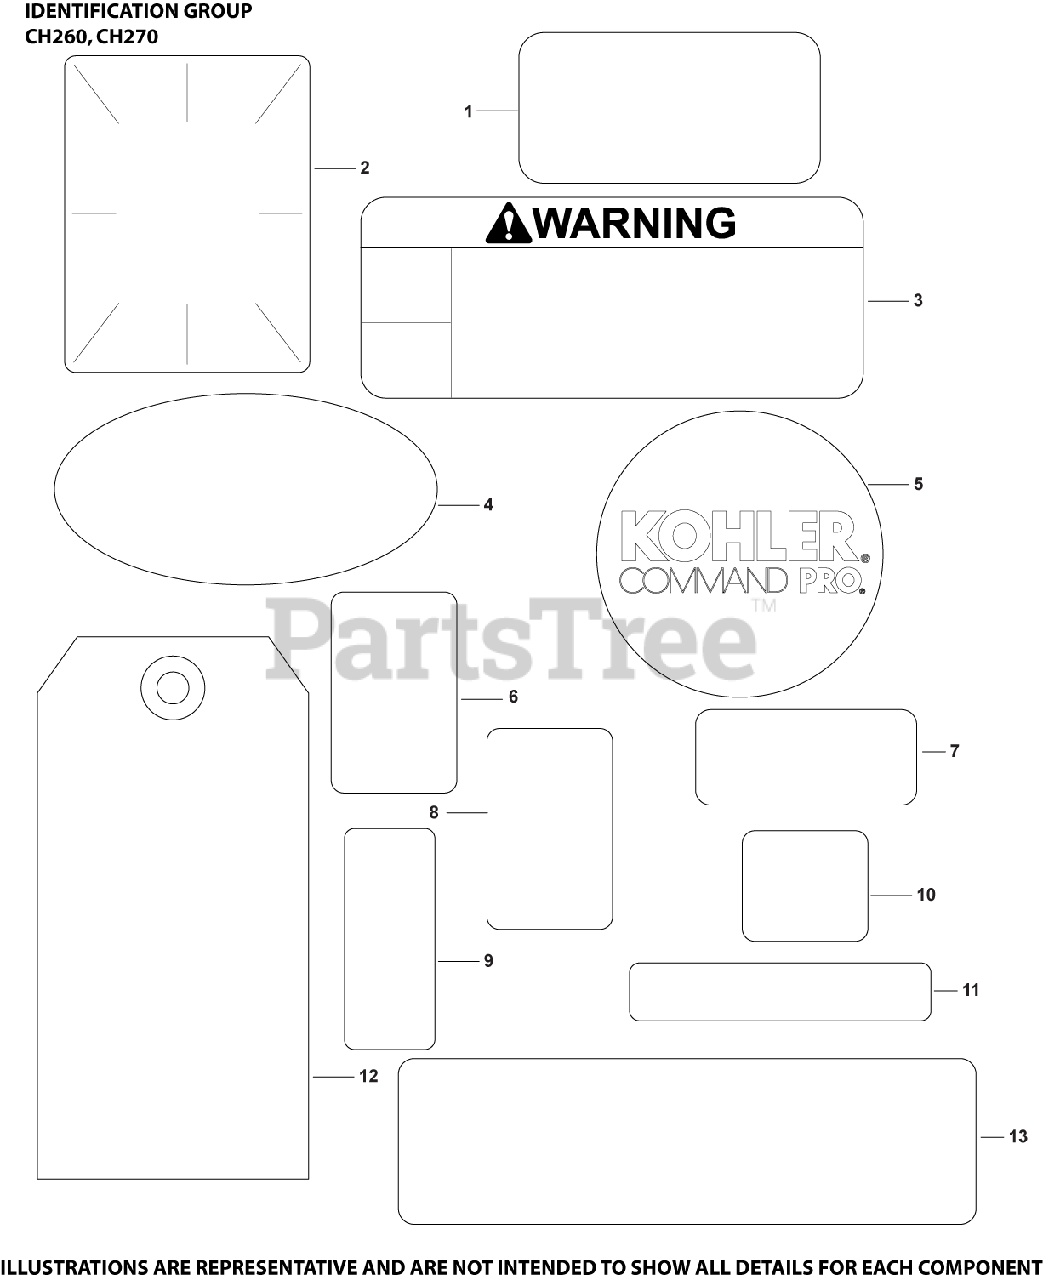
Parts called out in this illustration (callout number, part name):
1	DECAL, MAINTENANCE - USE 25 113 75-S
2	LABEL, CLEAR LAMINATION - USE 25 113 79-S
3	DECAL, WARNING
4	DECAL, QUAD CLEAN
5	DECAL, RECOIL USE 25 113 72-S Recoil Label
6	DECAL, SNOW FLAKE
7	DECAL, CANADIAN COMPLIANCE
8	DECAL, SUN
9	DECAL, FUEL SHUT OFF & CHOKE
10	DECAL, BASE ARROW
11	DECAL, THROTTLE
12	TAG, HANG
13	LABEL, 6 HP
